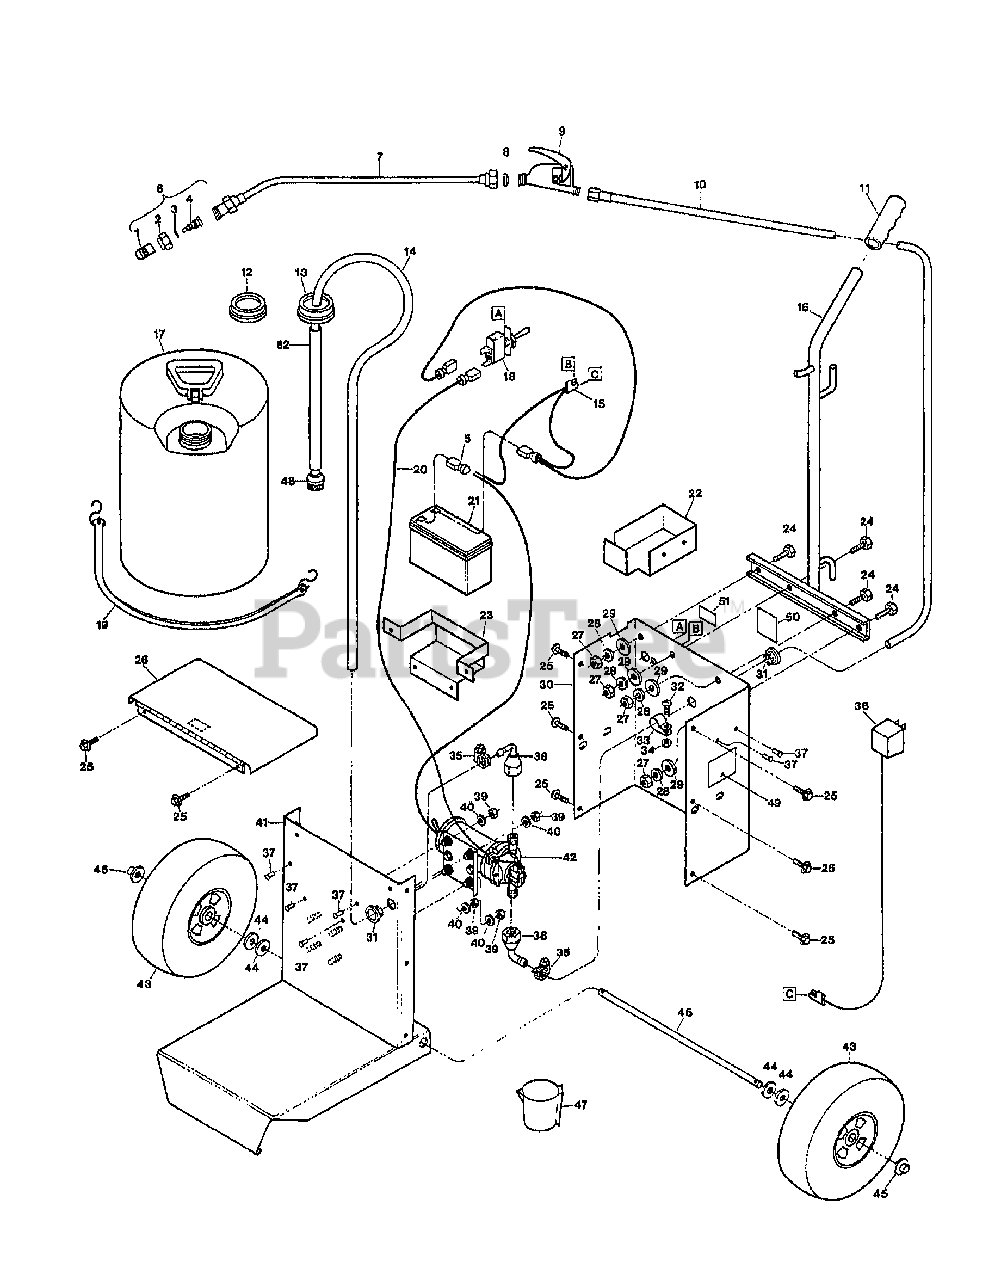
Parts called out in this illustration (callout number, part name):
5	WIRE-TERM 10882
6	ASSM-ADJ CONE W5500
7	EXTENSION-SPRAY 10825
8	WASHER-TEFLON/BRASS 10842
9	VALVE-SHUT OFF PISTOL 10824
10	HOSE W/FITTINGS 10845
11	GRIPS-HANDLEBAR
12	CAP-E/S TANK 10868
13	CAP W/HOLE 10869
14	HOSE-1/4" X 4' 10841
15	KIT-WIRE HARNESS 96517
16	ASSM-HANDLE
17	KIT-CAP & TANK
18	SWITCH-TOGGLE 10830
19	STRAP-RUBBER 10826
20	WIRE-ON/OFF-SWITCH PUMP
21	BATTERY-12V EL SPRAYER 10815
22	BRKT-ACCESSORY
23	ASSM-BATTERY BRKT
24	ENGINE-9436B
25	SCR-HW M10-24X.375 ZP
26	LID WITH HINGE
27	NUT-HEX 5/16-18 ZP
28	WASHER-LK .312 ZP
29	WASHER-1.25X.375X.1 ZP
30	ASSM-CHASSIS
31	BUSHING-SNP 10827
32	SCR-RH M10-32X.5 MACH
33	CLAMP-CABLE 10828
34	NUT-HH M10-32X.125
35	CLAMP-HOSE 10829
36	CHARGER-BATTERY TRAILBLAZER
37	RIVET-POP 1/8-3/8 10840
38	SWIVEL-90 ELBOW 10843
39	NUT-HEX M10-24
40	WASHER-#10
41	ASSM-CHASSIS
42	PUMP-SHURFLO 11511 5GAL
43	ASSM-TIRE & WHEEL
44	WASHER-1.75X.625X.11
45	NUT-PUSH 5/8
46	AXLE-EL SPRAY 10847
47	CUP-MEASURING 8OZ 10833
48	STRAINER-EL SPRAYER 10832
49	DECAL-SPRAYER LOGO 97122
50	DECAL-CHARGE 10817
51	DECAL-WARNING E/S 10818
52	1/2" PVC SCH40 11512
